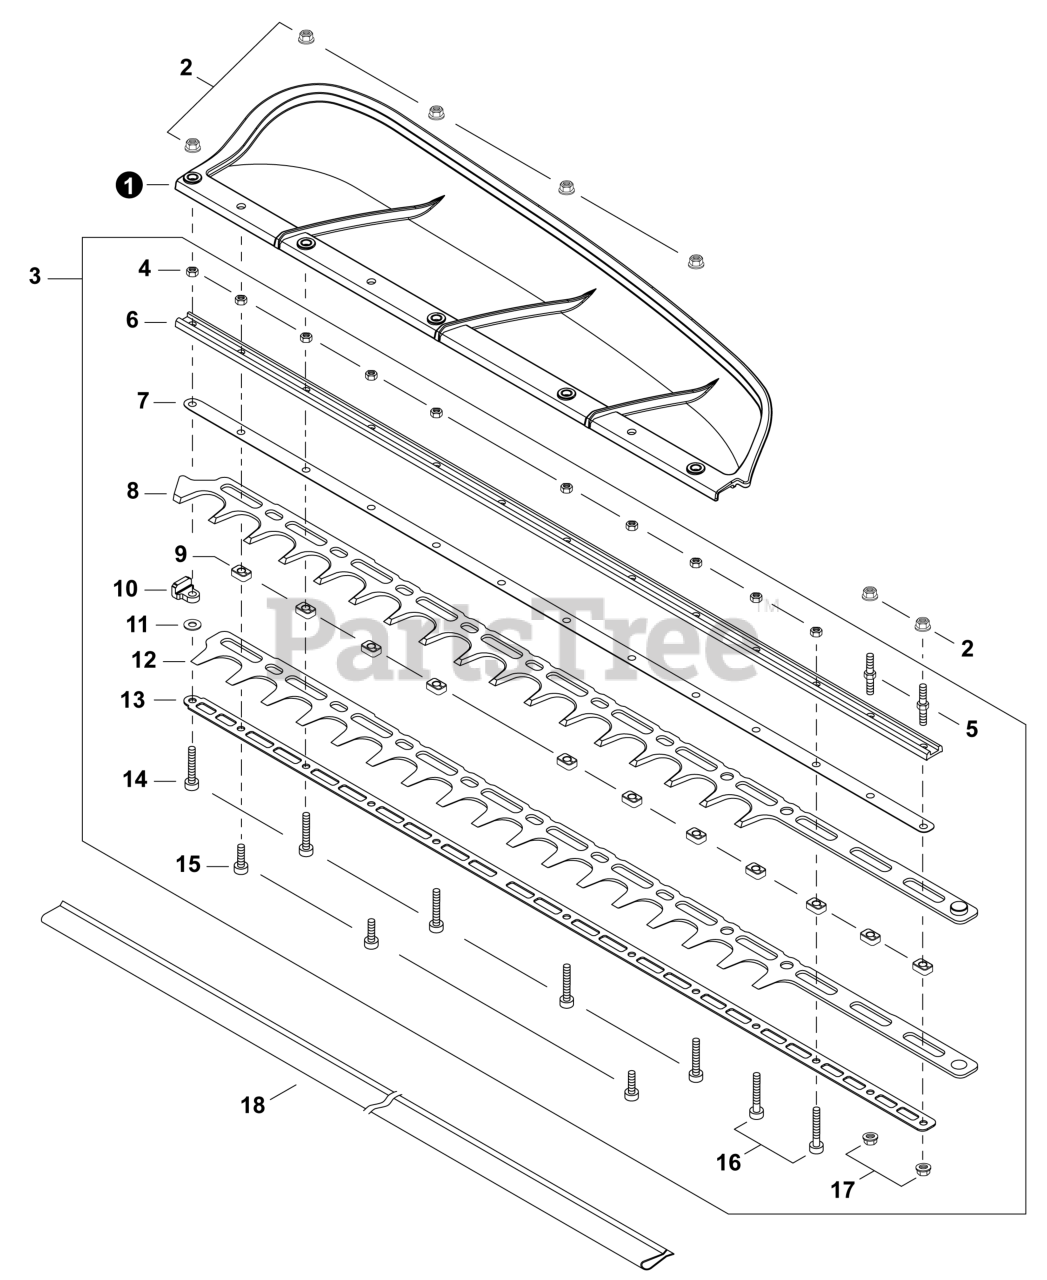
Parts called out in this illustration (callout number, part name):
1	DEFLECTOR, DEBRIS
2	NUT, FLANGE M5
3	CUTTER ASSY, 28"
5	STUD, MOUNTING M5x36
6	SUPPORT, BLADE 28"
7	SUPPORT, BLADE 28"
8	CUTTER 28"
12	CUTTER 28"
13	SUPPORT, BLADE 28"
14	BOLT, TORX 5x25
15	BOLT, TORX 5x16
16	BOLT, TORX 5x30
17	NUT, FLANGE M5
18	SCABBARD
